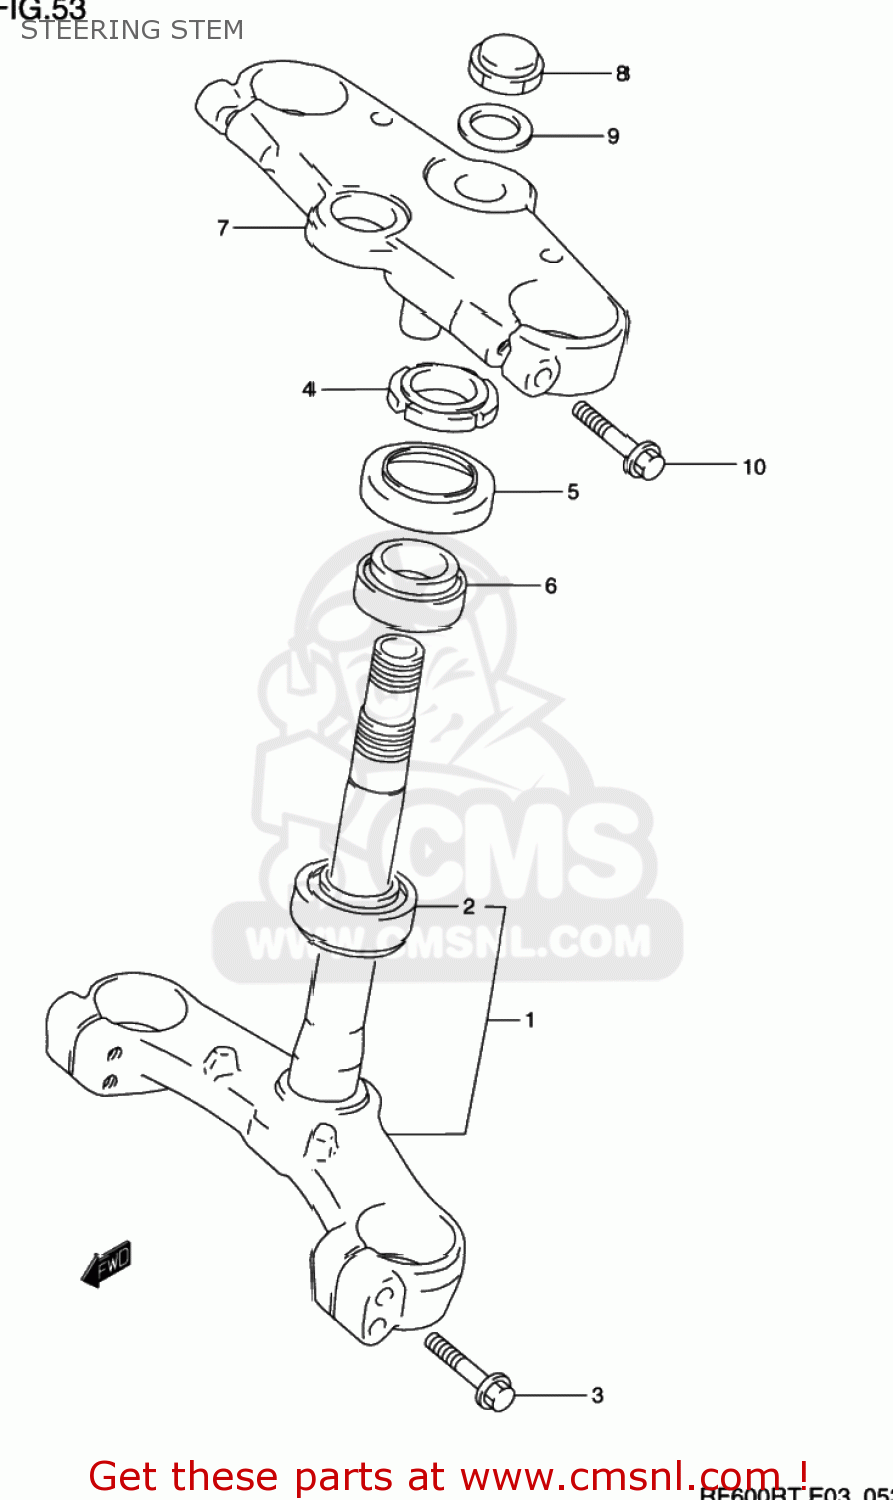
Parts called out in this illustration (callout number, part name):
1	STEM,STEERING
2	BEARING(30X55X17)
3	BOLT
4	NUT,STEERING STEM(25X44X10)
5	SEAL,STEERING UPR DUST
6	TAPER,ROLLER BEARING
7	HEAD,STEERING STEM
8	NUT,CAP
9	WASHER(22.5X32X1.6)
10	BOLT
